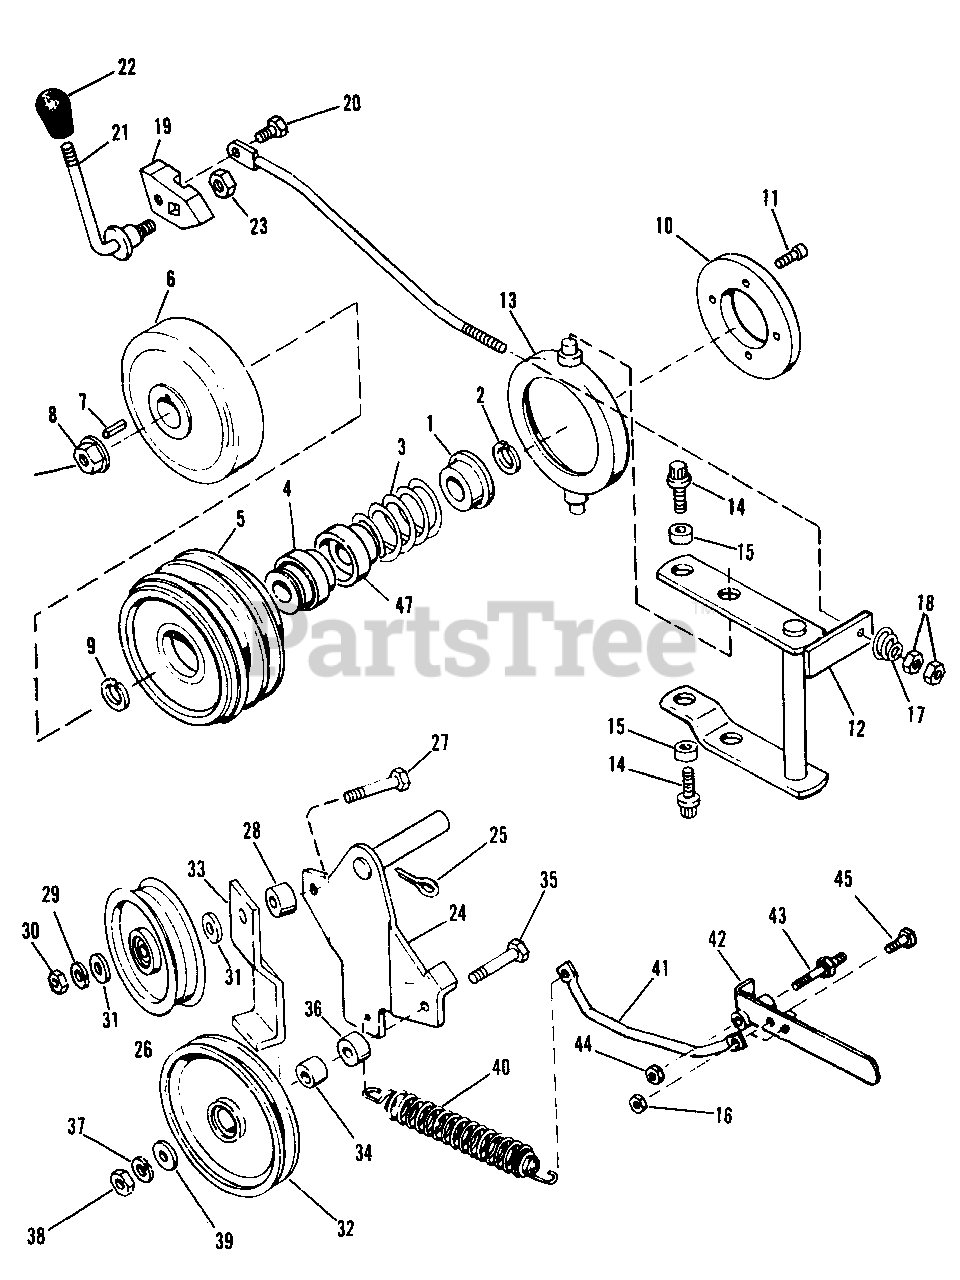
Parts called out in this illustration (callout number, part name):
1	GUIDE, Spring
2	RING, Retaining
4	BEARING ASSEMBLY
6	CLUTCH PLATE ASSEMBLY
8	NUT, Flange, Lock, 1/2"-13
9	RING, Retaining
10	DISK, Brake
11	SCREW, Socket Hd, 1/4"-20 x 5/8" lg.
12	PIVOT ASSEMBLY
13	SUPPORT, Brake Assembly
14	SCREW, Thread Forming
16	ROD, Control
17	SPRING, Conical
18	NUT, Hex, Full, 5/16"-18
20	CAPSCREW, Special, 5/16"-16 x 7/8" lg.
21	HANDLE, Clutch pto
22	KNOB
23	NUT, Hex, Full, Lock, 3/8"-16
24	PIVOT ARM ASSEMBLY
25	PIN, Cotter, 3/16" x 1-1/2" lg.
27	CAPSCREW, 3/8"-16 x 2" lg.
29	LOCKWASHER, 3/8"
30	NUT, Hex, Full, 3/8"-16
31	WASHER, Plain, 5/16"
32	PULLEY, Idler
33	STOP, Belt
35	CAPSCREW, Hex, 3/8"-16 x 2" lg.
37	LOCKWASHER, 3/8"
38	NUT, Hex, Full, 3/8"-16
39	WASHER, Plain, 5/16"
40	SPRING, Tension
41	ROD, Spring Tension
42	HANDLE ASSEMBLY
44	NUT, Hex, Full, Lock, 7/16"-14
45	CAPSCREW, Hex, 5/16" 18 x 3/4" lg.
46	NUT, Hex, Full, Lock, 5/16"-18
47	GUIDE, Spring
